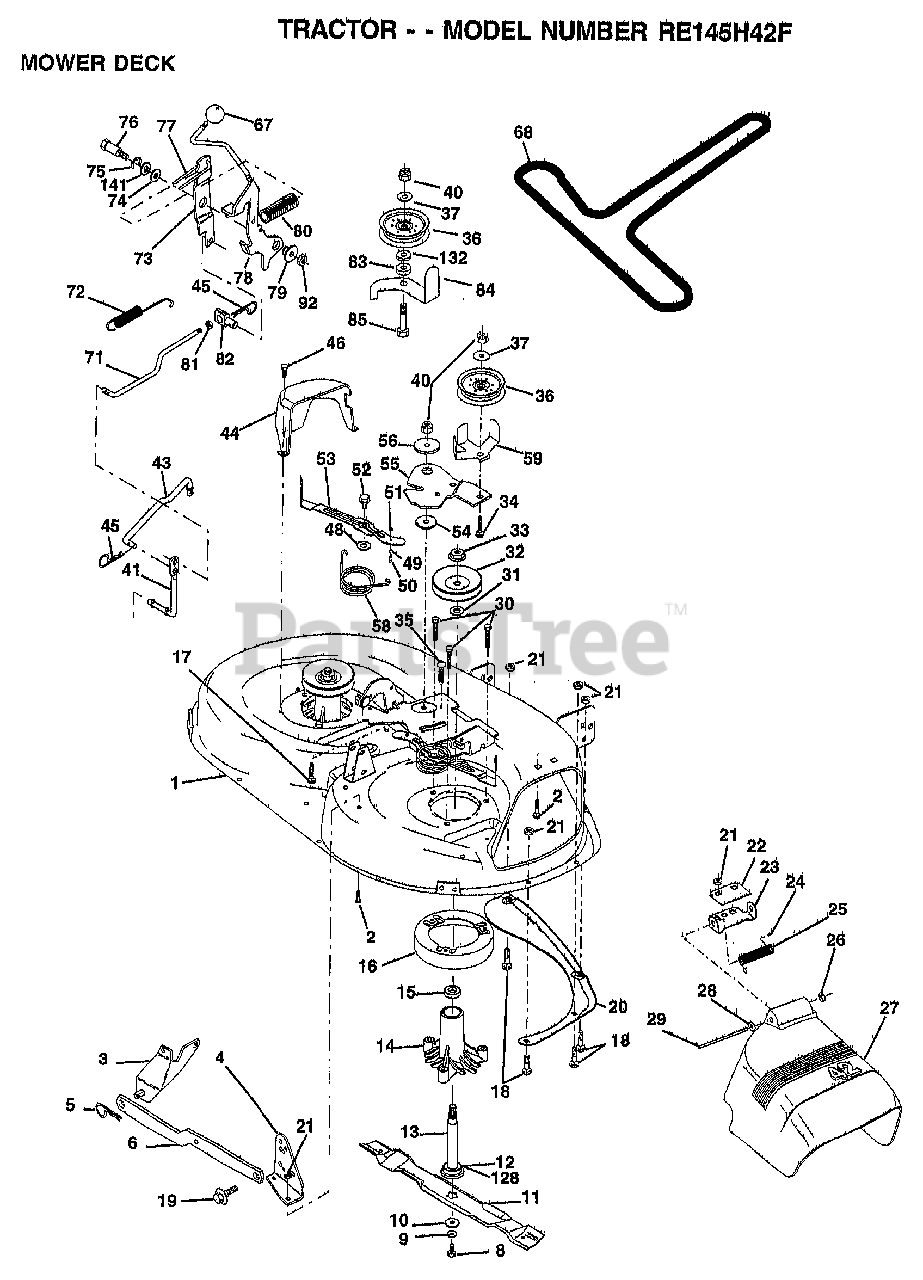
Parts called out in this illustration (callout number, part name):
1	"HOUSING ASSY.42"""
2	BOLT
3	BRKT ASM SWAY BAR
4	BRKT DECK SW BAR
8	BLADE BOLT
10	WASHER.HARD.BLADE
11	"BLADE.42"" HIPERF"
12	BEARING.BALL
14	HSG ASM MANDREL
15	BEARING
16	STRIPPER RND MWR
17	BOLT RDHD 3/8-16
18	BOLT
19	BOLT SHD 5/16-18
20	BAFFLE VORTEX 42
22	STIFFENER BRKT
23	DEFLECTOR BRKT
24	CAP-SLEEVE LT
25	SPRING TORSION
26	NUT PUSH M
27	DEFLECTOR.SHIELD
28	WASHER
29	HINGE ROD
30	"SCREW-THD ROLL,WA"
31	WASHER
32	PULLEY.MANDREL.42
34	BOLT
35	XMAS TREE FASTNER
36	FLAT IDLER PULLEY
37	WASHER
41	PIVOT ROD
43	ROD CLUTCH W/NIBS
44	GUARD MAND LH BLK
45	RETAINER M
46	SCREW.1/4-20X5/8
48	HARD SMALL WASHER
49	ROLLER ASM-CAM
50	SHOULDER BOLT
51	LOCKNUT
52	BOLT.SHLD.5/16-18
53	BRAKE PAD ARM ASM
54	HARDENED WASHER
55	ARM-IDLER
56	SPACER.RETAINER.MOWER
58	SPRING TORSN BRAK
59	GUARD IDLER TUV
67	KNOB.RD.7/16-14
68	BELT.V.T-PATH
71	ROD CLUTCH 38/42
72	RETURN SPRING
73	CLUTCH ARM SECOND
74	WASHER
75	RING
76	SHOULDER BOLT
77	SPRING KEEPER
78	LEVER.ASM.CLUTCH
79	BUSHING
80	SPRING.CLUTCH.MWR
81	NUT
82	TRUNION ADJ
83	WASHER
84	"KEEPER-BELT,FIXED"
85	BOLT
92	NUT
128	WASHER.FELT.
132	WASHER GT
141	WASHER .T
